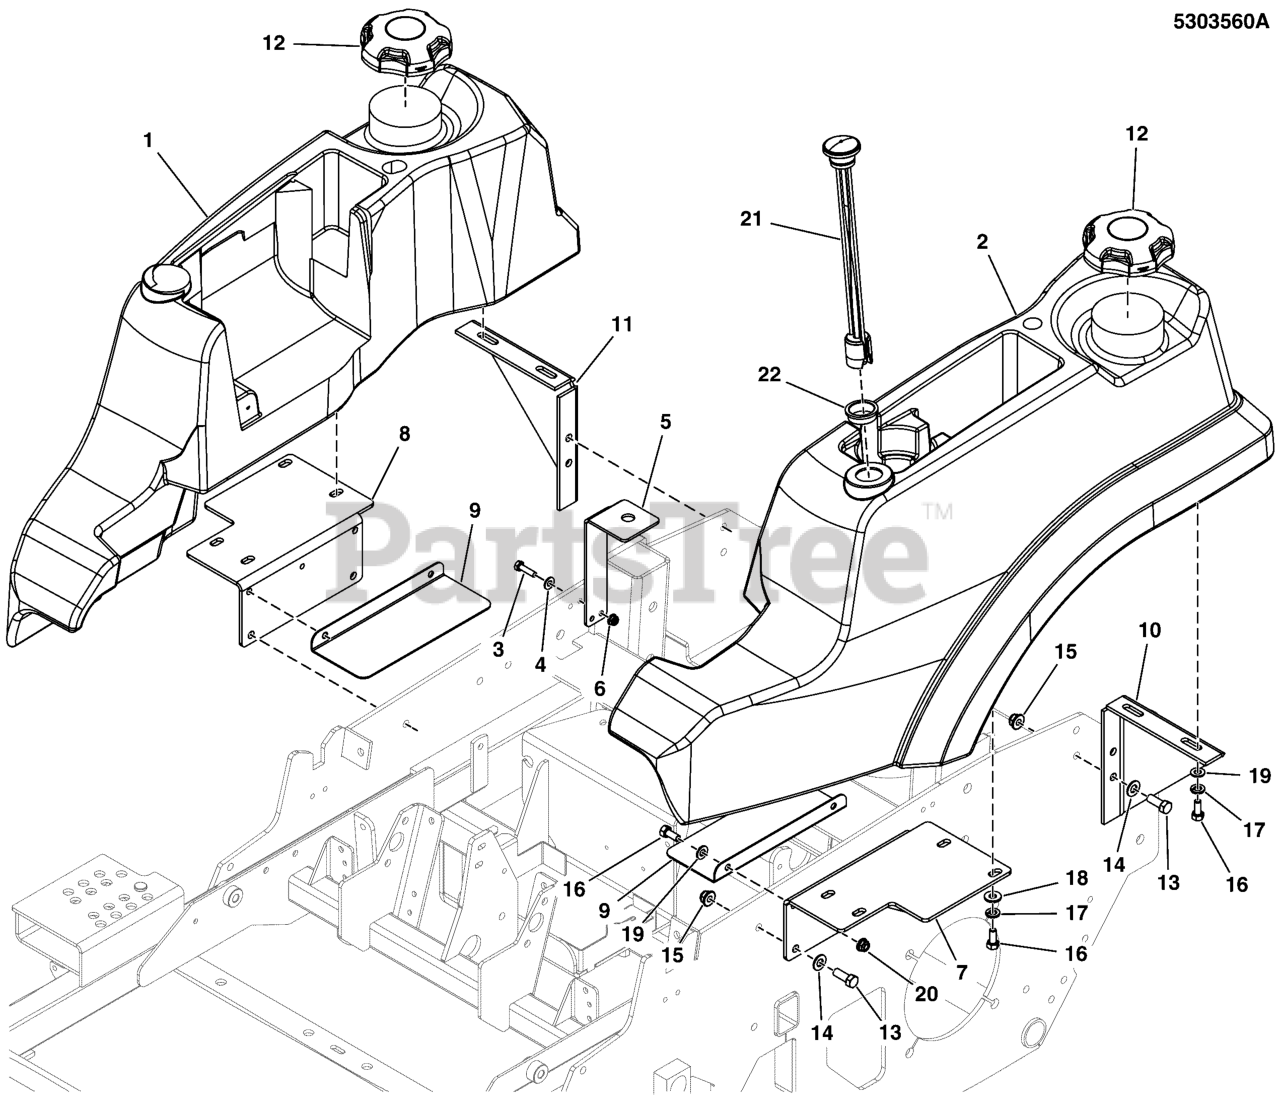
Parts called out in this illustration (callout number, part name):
1	TANK, FUEL, 5 GAL, SNP-PRO, RH, 2013
2	TANK, FUEL, 5.75 GAL, SNP-PRO, LH, 2013
3	BOLT, 1/4-20 X 3/4 GD5 CZ
4	WASHER, 1/4 SAE
5	PLATE, FUEL SWITCH - BLK
6	NUT, 1/4-20 HEX NYLOCK FLANGE
7	WELD, FUEL TANK MOUNT, S150XT, LH - RED
8	WELD, FUEL TANK MOUNT, S150XT, RH - RED
9	GUARD, FAN - BLK
10	MOUNT, REAR TANK, LH - BLK
11	MOUNT, REAR TANK, RH - BLK
12	FUEL CAP, 3-1/2", MANAGED VENT OUT, 12"
13	BOLT, 3/8-16 X 1" GD5 CZ
14	WASHER, 3/8 SAE
15	NUT, 3/8-16 HEX NYLOCK FLANGE
16	BOLT, 5/16-18 X 3/4 GD5
17	WASHER, 5/16 LOCK CZ
18	WASHER, 5/16 F436 FLAT
19	WASHER, 5/16" SAE
20	NUT, 5/16-18 HEX NYLOCK FLANGE
21	GAUGE, FUEL, 12
22	GROMMET, FUEL GAUGE (SV)
